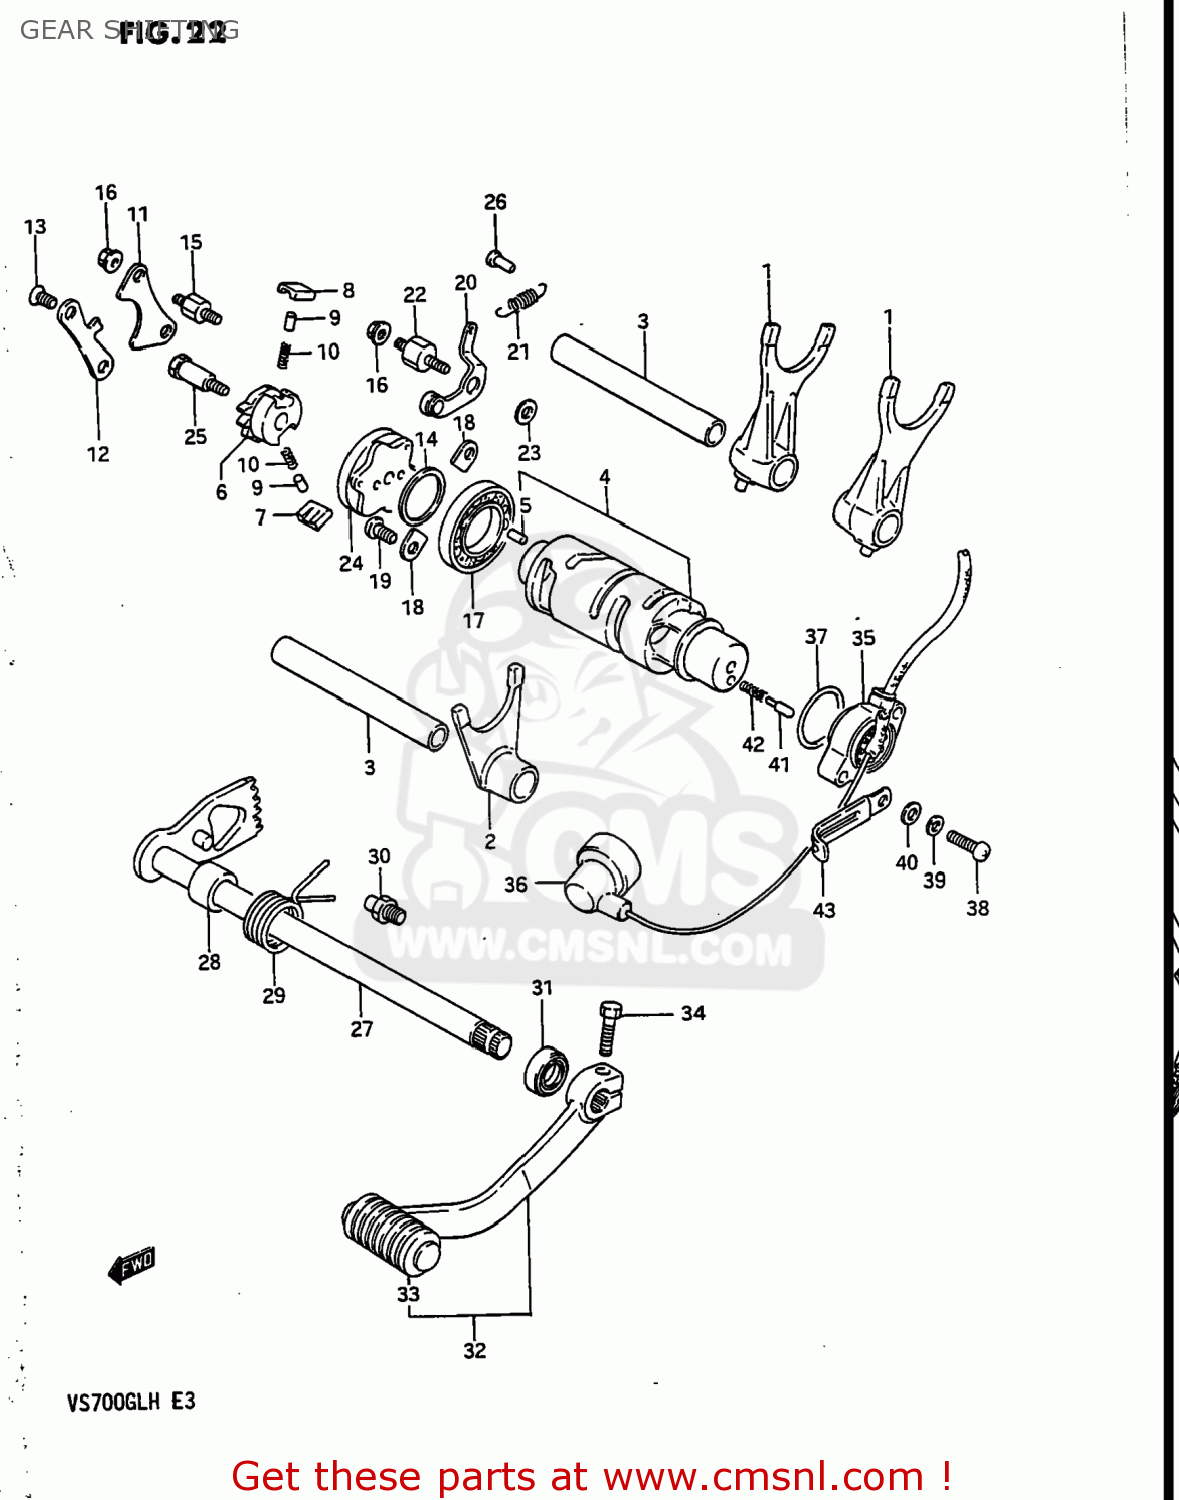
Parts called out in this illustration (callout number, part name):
1	FORK,GEAR SHIFT NO.1
2	FORK,GEAR SHIFT NO.2
3	SHAFT,GEAR SHIFT FORK(L:115)
4	CAM,GEAR SHIFT
5	PIN
6	GEAR,GEARSHIFT CAM DRIVE
7	PAWL,GEAR SHIFT NO.1
8	PAWL,GEAR SHIFT NO.2
9	PIN(5X8)
10	SPRING
11	LIFTER,GEAR SHIFT POLE
12	GUIDE,GEAR SHIFT CAM
13	SCREW
14	WASHER(25X32X3)
15	BOSS,SHIFT PAWL LIFTER
16	NUT
17	BEARING
18	RETAINER,SHIFT CAM,R BEARING
19	SCREW 6X12
20	STOPPER,GEAR SHIFT CAM
21	SPRING
22	SUPPORT,CAM STOPPER ARM
23	WASHER
24	PLATE,GEAR SHIFT CAM
25	PIN,SHIFT CAM DRIVEN GEAR
26	RIVET
27	SHAFT,GEAR SHIFT
28	SPACER(12X20X15.3)
29	SPRING
30	STOPPER,GEAR SHIFT CAM
31	OIL SEAL
32	LEVER ASSY,GEAR SHIFT
33	RUBBER,GEAR SHIFT PEDAL
34	BOLT
35	BASE,NEUTRAL SWH TERMINAL
36	CAP,OIL PRESSURE SWITCH
37	O RING(D:2.4,ID:26.2)
38	SCREW 5X20
39	LOCK WASHER
40	WASHER
41	PIN(5X15.5)
42	SPRING
43	CLAMP
